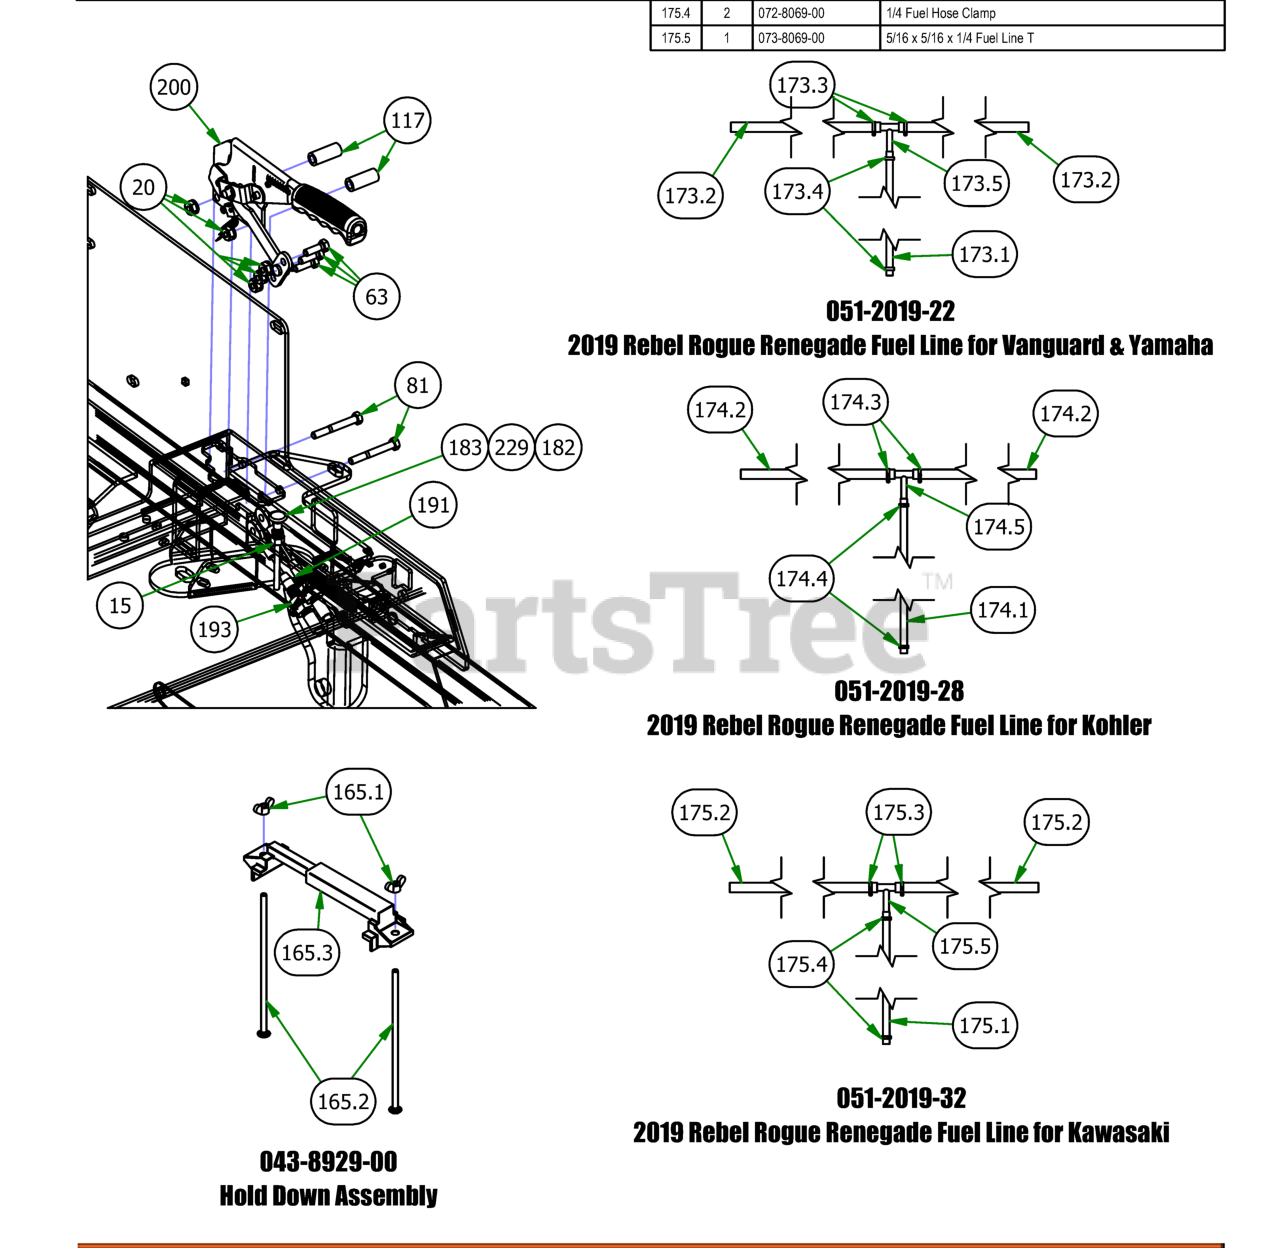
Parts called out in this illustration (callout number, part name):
15	3/8" Fine Threaded Jam Nut
20	5/16-18 Nylon Flange Nut
63	5/16" x 1" Bolt
81	5/16" x 2 1/2" Bolt
117	2019 Outlaw Brake Handle Spacer .625 x 1.5
165.1	1/4-20 WING NUT FORGED (TYPE A) LIGHT SERIES ZINC
165.2	1/4-20 X 8 CARRIAGE BOLT (MIN 6" THREAD) ZINC
165.3	Battery Hold Down
173.1	1/4" Fuel Line Hose
173.2	5/16" fuel line hose
173.3	5/16 Fuel Line Clamp
173.4	1/4 Fuel Hose Clamp
173.5	5/16 x 5/16 x 1/4 Fuel Line T
174.1	1/4" Fuel Line Hose
174.2	5/16" fuel line hose
174.3	5/16 Fuel Line Clamp
174.4	1/4 Fuel Hose Clamp
174.5	5/16 x 5/16 x 1/4 Fuel Line T
175.1	1/4" Fuel Line Hose
175.2	5/16" fuel line hose
175.3	5/16 Fuel Line Clamp
175.4	1/4 Fuel Hose Clamp
175.5	5/16 x 5/16 x 1/4 Fuel Line T
183	Choke for 36Hp Vanguard & FX1000 Kawasaki
191	2019 Short Brake Cable-Suspension Models
193	2019 Long Brake Cable-Renegade, Rogue
200	2019 Brake Handle Assembly
229	Code Indicator Light
